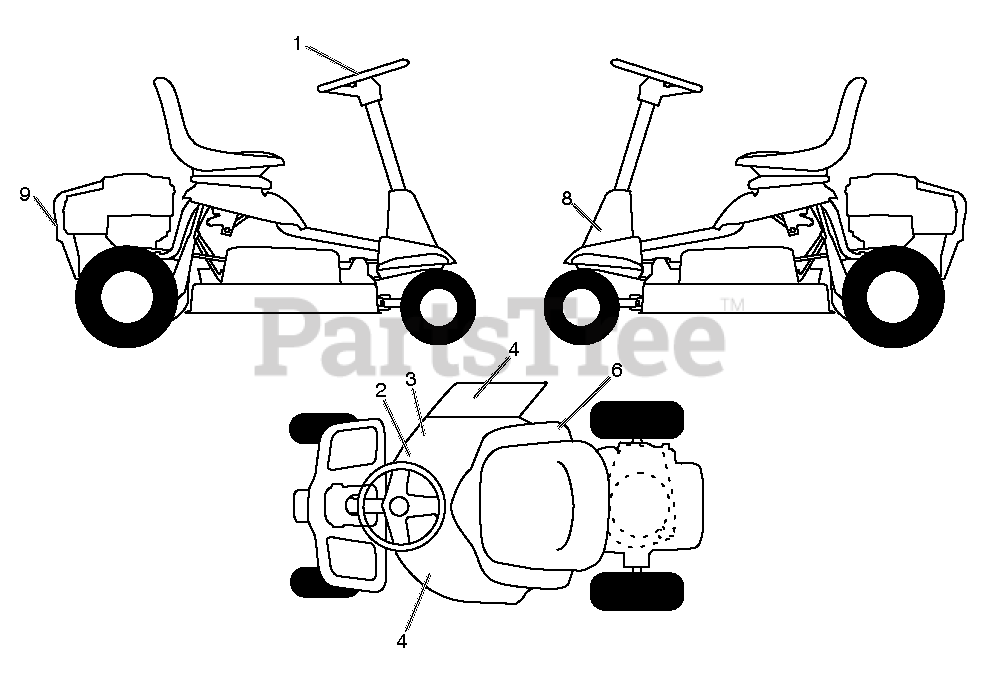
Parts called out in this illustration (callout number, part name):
1	Steering Wheel Decal
2	Decal, V-Belt Sch 30"
3	DECAL.WARN.DFLCTR/CTFRG.SRD
4	DECAL.DCK/DEF.LRV.26".WEEDEATE
